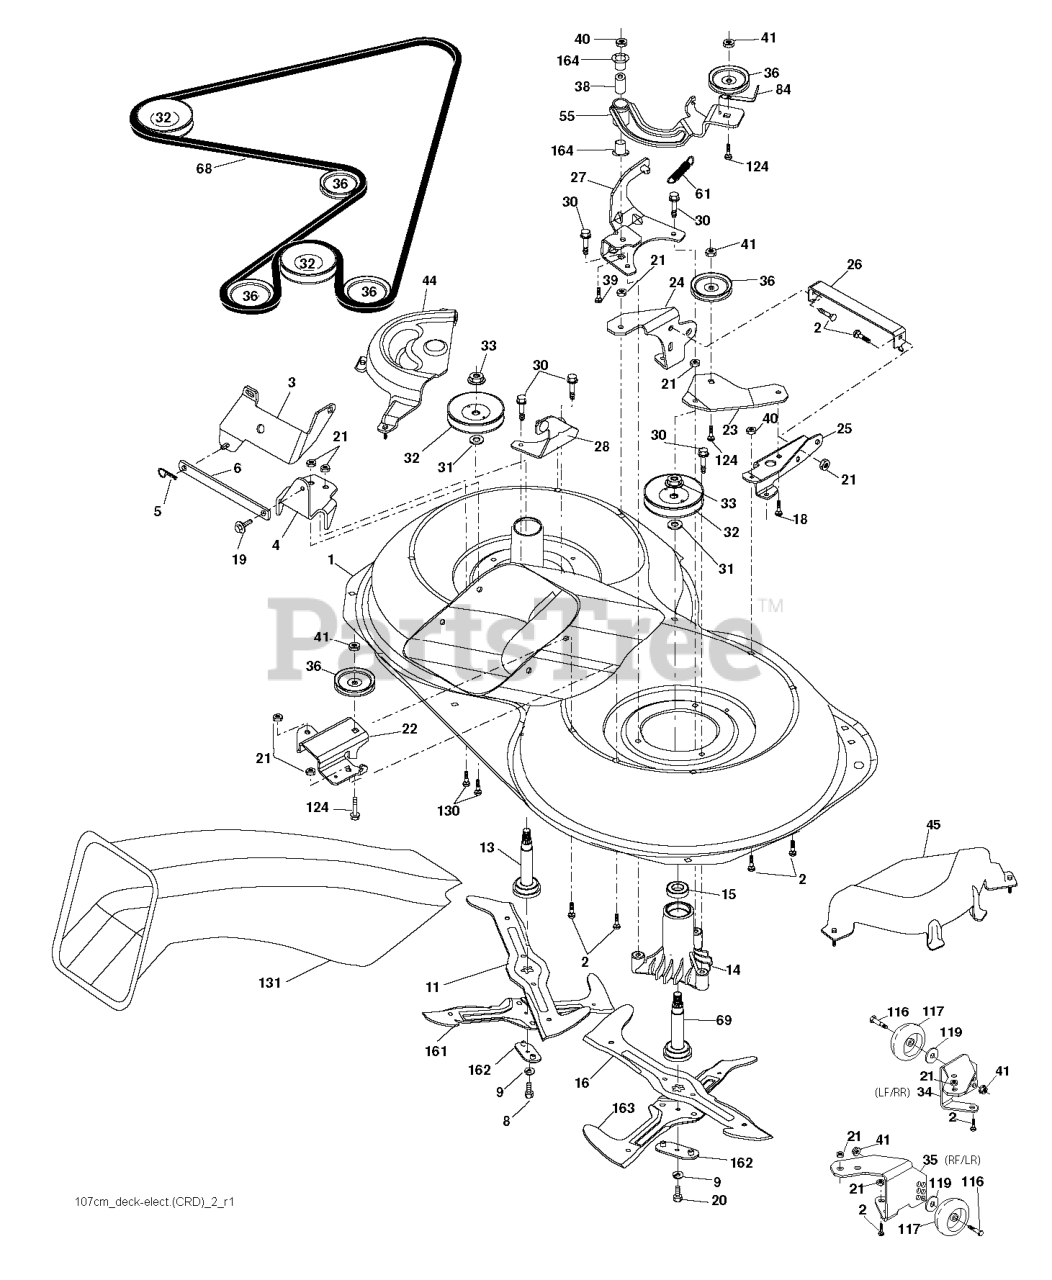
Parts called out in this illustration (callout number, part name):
1	Housing Asm. Mower 107 CRD
2	RP BOLT 5/16-18 X3/4 ZN/YEL GR
3	BRACKET.ASM.BAR.SWAY.CHASS
5	RETAINER-SPRNG RB
6	BAR.SWAY.92.CRD
8	BOLT.3/8-24X1.25 GR8
9	LOCKWASHER
11	BLADE.3N1.LH.CRD
13	SHAFT ASM VENT
14	HOUSING.MANDREL.VENTED (MACHD)
16	BLADE.3N1.RH.CRD
19	BOLT SHD 5/16-18
20	BOLT.3/8-24X1.25GR8. LHTHRD
21	LOCKNUT
22	BRACKET.IDLER.RR.107.CRD
24	BRACKET
25	BRACKET RF
26	SUPPORT
28	BRACKET
30	SCREW, WASHER HEAD
31	WASHER.SPACER.MANDREL
32	PULLEY.MANDREL.4.80 PD.2006
33	NUT.FLANGE.LOCK.TOP
34	BRACKET
35	BRACKET
36	PULLEY.IDLER.4.25
41	NUT LOCK FLG 3/8-16 UNC
45	COVER.MANDREL.RH.CRD
46	SCREW.1/4-20X5/8
55	ARM.IDLER.107.CRD
61	SPRING
68	HEX-BELT 107 MOWER
69	SHAFT.ASM.W/LWR.BRG.RH.THREAD
84	KEEPER, BELT IDLER
116	BOLT.SHOULDER.3/8-16X3-5/8.
117	RP WHEEL. GUAGE RALLY
119	WASHER
124	BOLT.3/8-16X1.50
130	BOLT.CARR.SQNK.5/16-18UNC.X3/4
131	CHUTE BAGGER
163	BLADE.CROSS.RH.CRD.107
164	BRNG T
